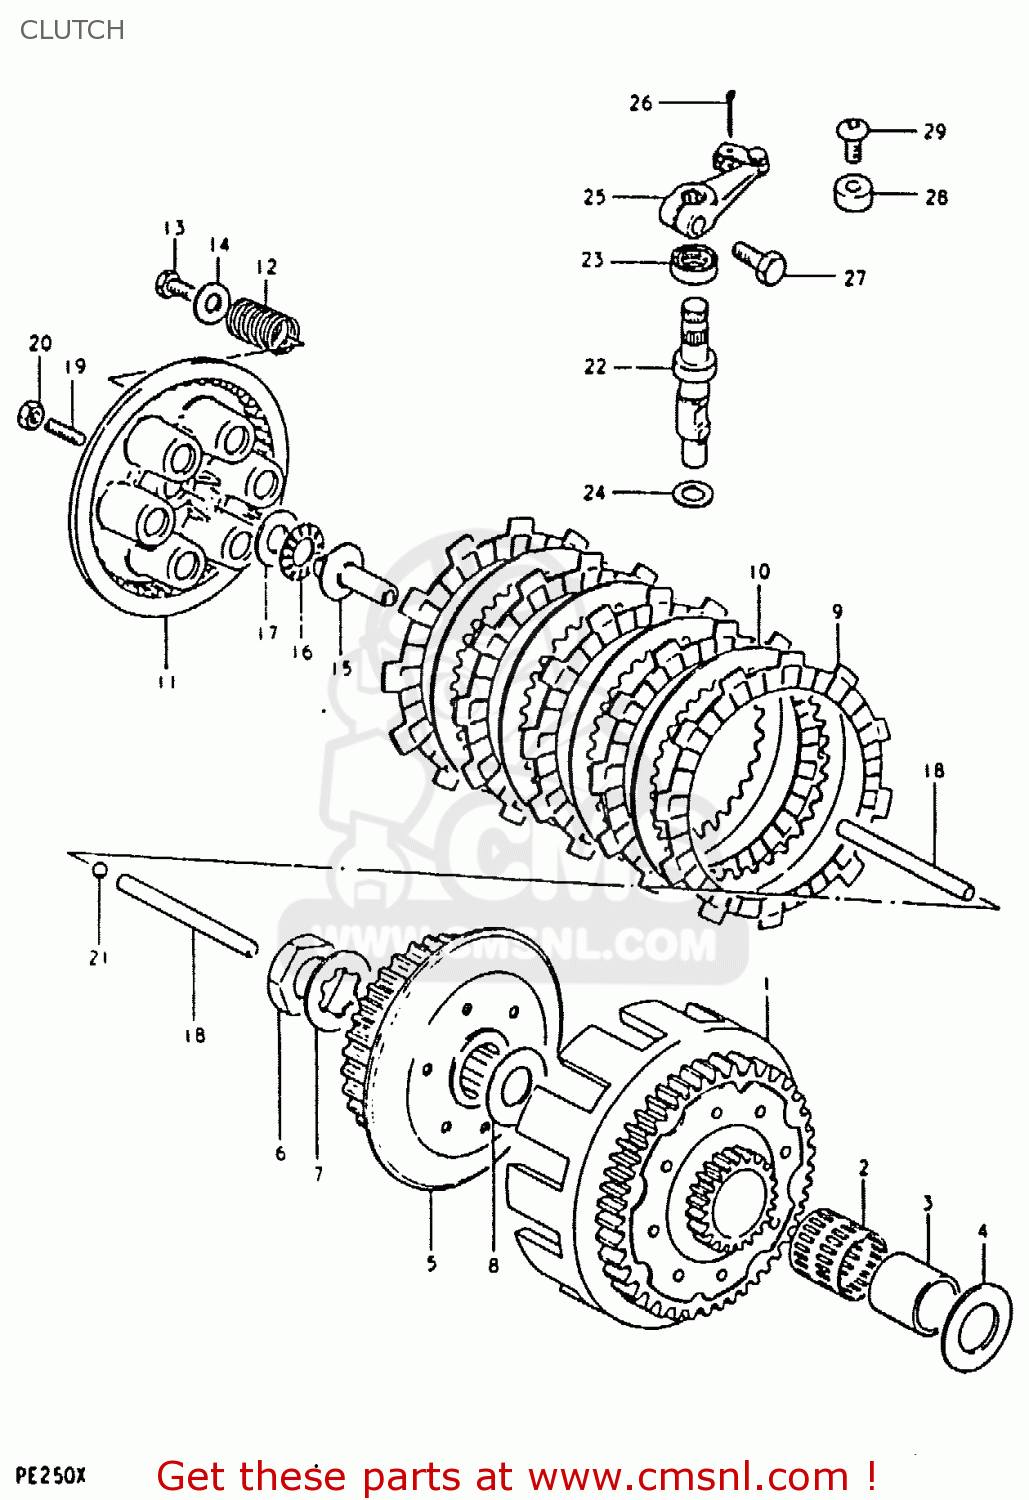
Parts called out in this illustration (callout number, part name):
1	GEAR ASSEMBLY,PRIMARY DRIVE
2	ROLLER BEARING (25X30X2
3	SPACER
4	WASHER(20X38X2)
5	HUB,CLUTCH SLEEVE
6	NUT (20MM)
7	WASHER,LOCK
8	WASHER(20X38X2)
9	PLATE,CLUTCH DRIVE (MCA)
10	PLATE,CLUTCH DRIVEN (NAS)
11	DISC,CLUTCH PRESSURE
12	SPRING
13	BOLT, UPPER
14	WASHER
15	PIECE,CLUTCH PUSH
16	BEARING(15X28X2)
17	WASHER
18	ROD,CLUTCH PUSH
19	SCREW
20	NUT 6MM
21	BALL
22	SHAFT,CLUTCH RELEASE C
23	OIL SEAL
24	WASHER (14.2X22X1)
25	ARM,CLUTCH RELEASE
26	PIN
27	BOLT
28	GUIDE,CLUTCH CABLE
29	SCREW
